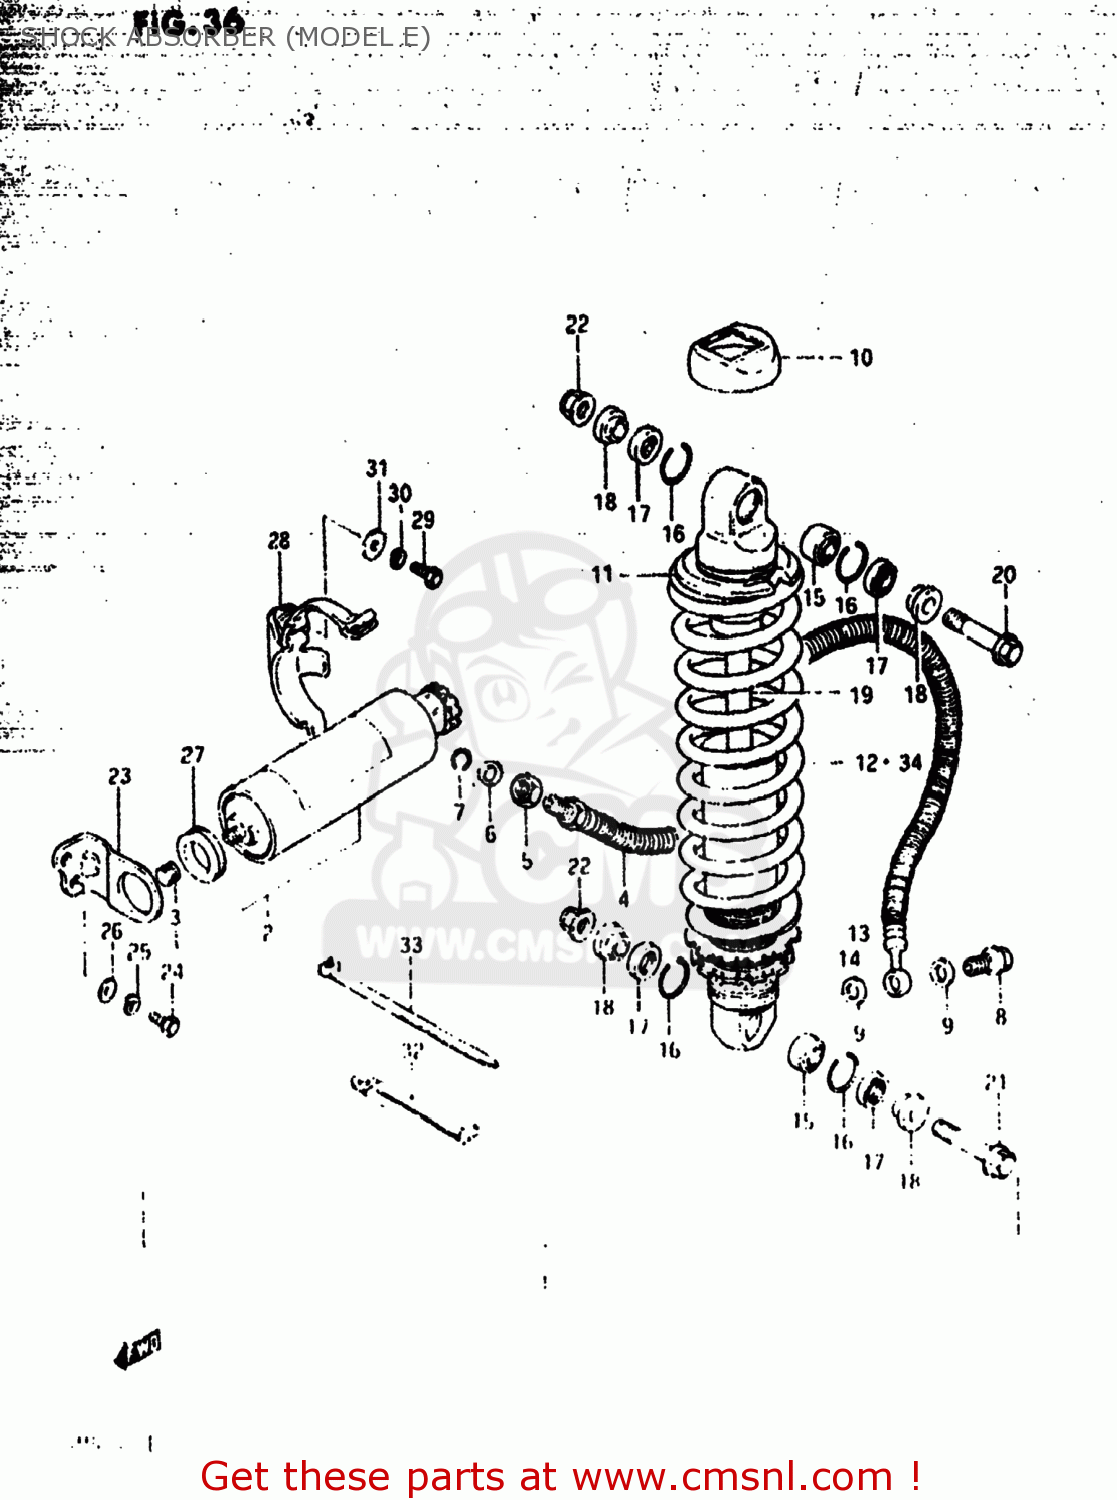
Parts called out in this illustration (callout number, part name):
1	ABSORBER ASSEMBLY,REAR SHOCK
2	RESERVE TANK,REAR SHOCK
3	CAP
4	HOSE,REAR SHOCK ABSORBER
5	NUT 12MM
6	WASHER,REAR SHOCK HOSE
7	O-RING,RESERVE TANK
8	BOLT,REAR SHOCK ABSORBER
9	GASKET (NAS)
10	CAP
11	GUIDE,REAR SHOCK ABSORBER SPRING
12	SPRING
13	GUIDE,SPRING
14	GUIDE,REAR SHOCK ABSORBER SPRING
15	BEARING,REAR SHOCK ABSORBER
16	RING
17	SEAL,DUST
18	SPACER
19	ROD,PISTON
20	BOLT,REAR SHOCK ABSORBER
21	BOLT(10X58)
22	NUT
23	BRACKET,RESERVOIR TANK
24	BOLT
25	LOCK WASHER
26	WASHER
27	CUSHION
28	BRACKET,RESERVOIR TANK
29	BOLT, UPPER
30	LOCK WASHER
31	WASHER
32	CLAMP
33	CLAMP
34	SPRING
